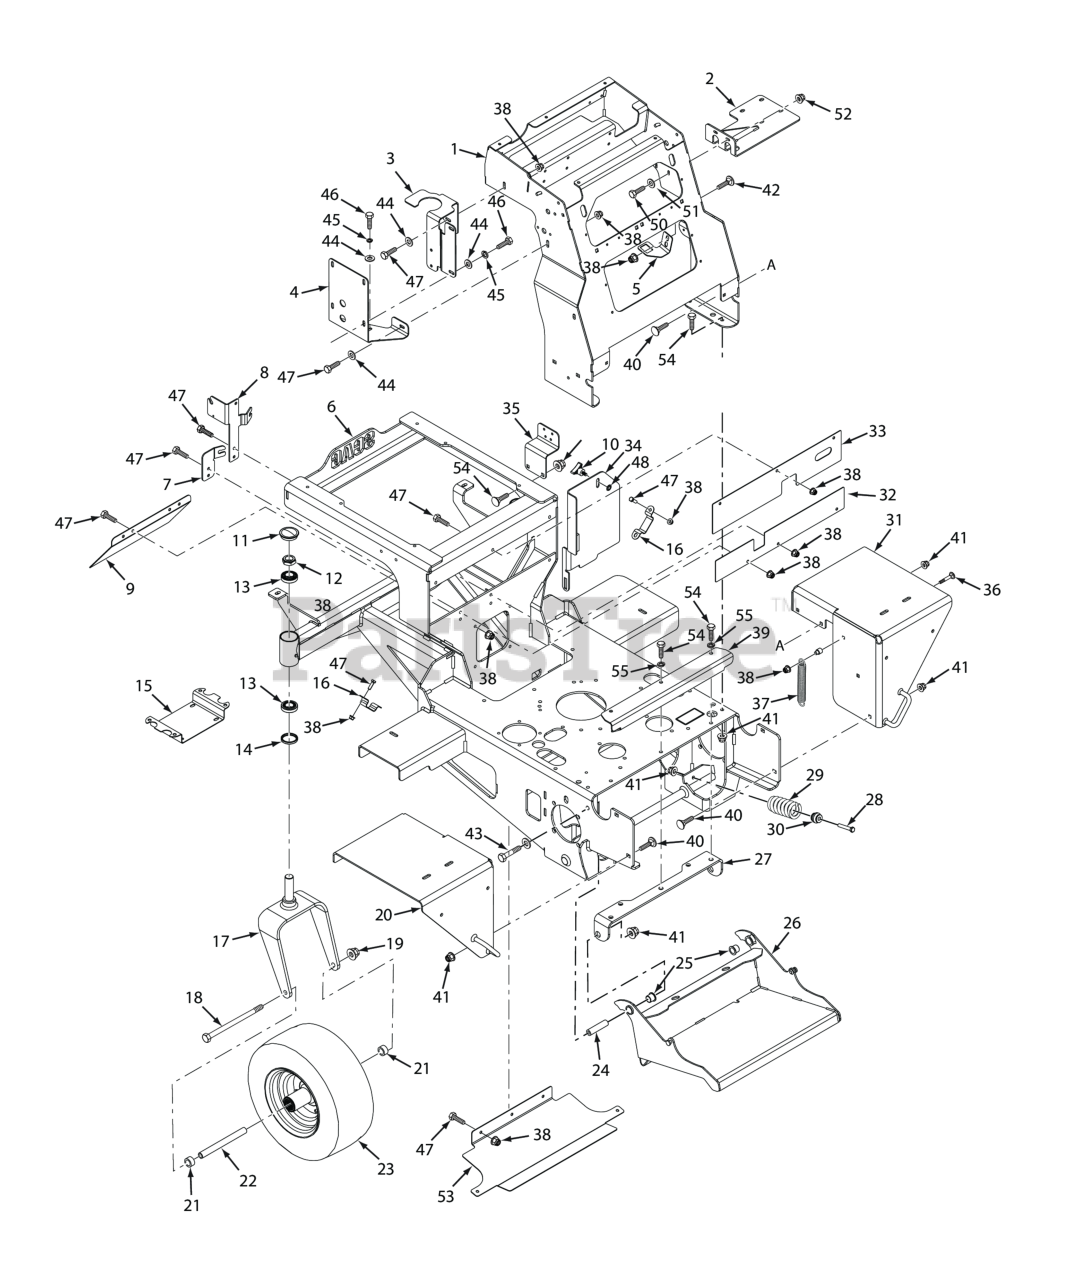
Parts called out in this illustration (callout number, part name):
1	Handlebar Weldment
2	Mounting Bracket, Hose Reel
3	Mounting Bracket, Oil Reservoir
4	Mounting Bracket, Fuel Tank
5	Mounting Bracket, Brake Switch
6	Mainframe Weldment, STS
7	Mounting Bracket, Door Cable
8	Mounting Bracket, Cable
9	Cover, Vent
10	Knob, w/ Stud, 5/16 - 18
11	Cap, Grease
12	Nut, Hex Elastic Stop 1.0"-14
13	Bearing Cone
14	Upright Post Weldment, RH
15	Mounting Bracket, Foamer Accessory (optional)
16	Bracket, Hose
17	Caster Yoke Weldment
18	Bolt, Hex Head 1/2-13 x 9-1/2" (61V & 72A/VS)
19	Nut, Elastic Stop 1/2-13, (STT-52 & STTII-52)
20	Fender, LH
21	Spacer, Caster Wheel
22	Sleeve, Caster Wheel (61V, 72A/VS)
23	Caster Wheel Assembly, 16 x 6.50 - 8
24	Spacer
25	Bearing, .750 I.D. Plastic
26	Footplate Assembly (Incl. #25)
27	Footplate Weldment
28	Bolt, Hex Head 3/8-16 x 2-1/4" - Stainless Steel
29	Spring, Suspension Platform
30	Mount, Spring
31	Fender, RH
32	Guard, Rear Hopper Lower
33	Guard, Rear Hopper Uppler
34	Battery Door
35	Mounting Bracket, Strainer
36	Bolt, Carriage 5/16-18 x 1.75 - Stainless Steel
37	Spring,Counter Balance
38	Locknut, 5/16-18 Flg. Elastic Stop - Stainless Steel
39	Mounting Bracket, Operator Presence
40	Bolt, Carriage 3/8-16 x 1.0 - Stainless Steel
41	Nut, Flange Elastic Stop 3/8 - 16 - Stainless Steel
42	Bolt, Carriage 5/16 - 18 x 1" - - Stainless Steel
43	Bolt, Hex 3/8 - 16 x 4.00 - Stainless Steel
44	Washer, Flat 5/16 -.375 x .875 x .0547/.104 - Stainless Steel
45	Washer, Lock 5/16 Spring - Stainless Steel
46	Bolt, Hex 5/16 - 18 x .75 - Stainless Steel
47	Bolt, Hex 5/16" - .375 x 1.00- Stainless Steel
48	Nut, Push On - Stainless Steel
49	Spring Bracke, Footplate
50	Bolt, Hex 1/4 - 20 x 1.00
51	Locknut, 1/4 - 20 Flg. Elastic Stop - Stainless Steel
52	Washer, Flat 1/4-.281X.625X.080 - Stainless Steel
53	Muffler Heat Shield
54	Bolt, Hex Head 3/8 - 16 x 1.50 - Stainless Steel
55	Lockwasher, 3/8-.377 x .680 x 094
